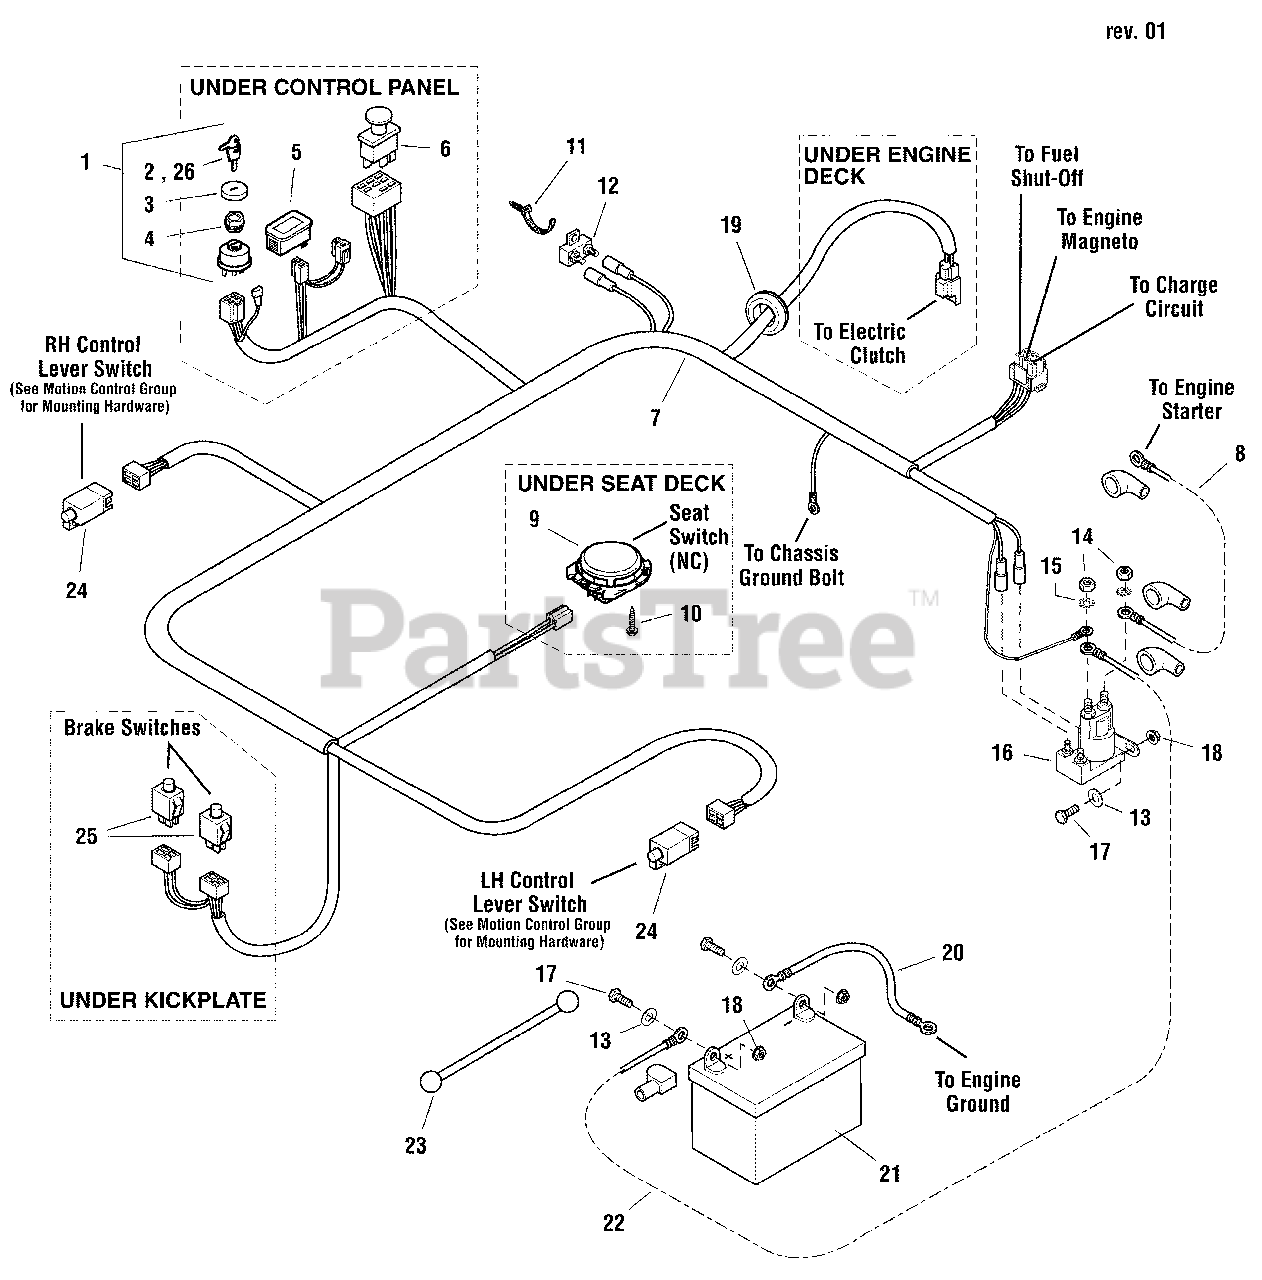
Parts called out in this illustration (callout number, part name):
1	SWITCH ASMY-IGNITION INDAK NO KEYS
2	KEYS, BLISTER PK KIDS+MWRS DON'T MIX
4	PLASTIC NUT
5	HOUR METER, DIGITAL
6	SWITCH, PTO
7	WIRE HARNESS, SNAPPER Z
8	BATTERY CABLE, POSITIVE, 22"
9	SWITCH, SEAT, GRAY, NC (BOLT IN)
9	SWITCH, SEAT, GRAY, NC (TWIST IN)
10	BOLT, HEX WASHER HEAD PLASTITE, 1/4 X 1/2
11	CABLE TIE-PUSH MOUNT
12	CIRCUIT BREAKER, 20A
13	WASHER, 1/4 SAE (5025154)
14	NUT, HEX JAM, 5/16-24
15	WASHER, LIGHT LOCK, 5/16
16	SOLENOID-4 POLE 12 VOLT DC (TROMBETTA)
17	BOLT, 1/4-20 X 3/4" GD5 YZ
18	NUT, 1/4-20 HEX SERR. FLANGE
19	GROMMET, 7/8
20	BATTERY CABLE, NEGATIVE, 22"
21	BATTERY, WET ( BCIU1, 340 CCA)
22	BATTERY CABLE, POS, 15, 1/4-5/16
23	STRAP-BLACK RUBB
24	SWITCH, PLUNGER, N.O./N.C.
25	SWITCH, DP NO/NC SNAP-IN
26	KEYS, BLISTER PK KIDS+MWRS DON'T MIX, EXP, CE MODELS ONLY
